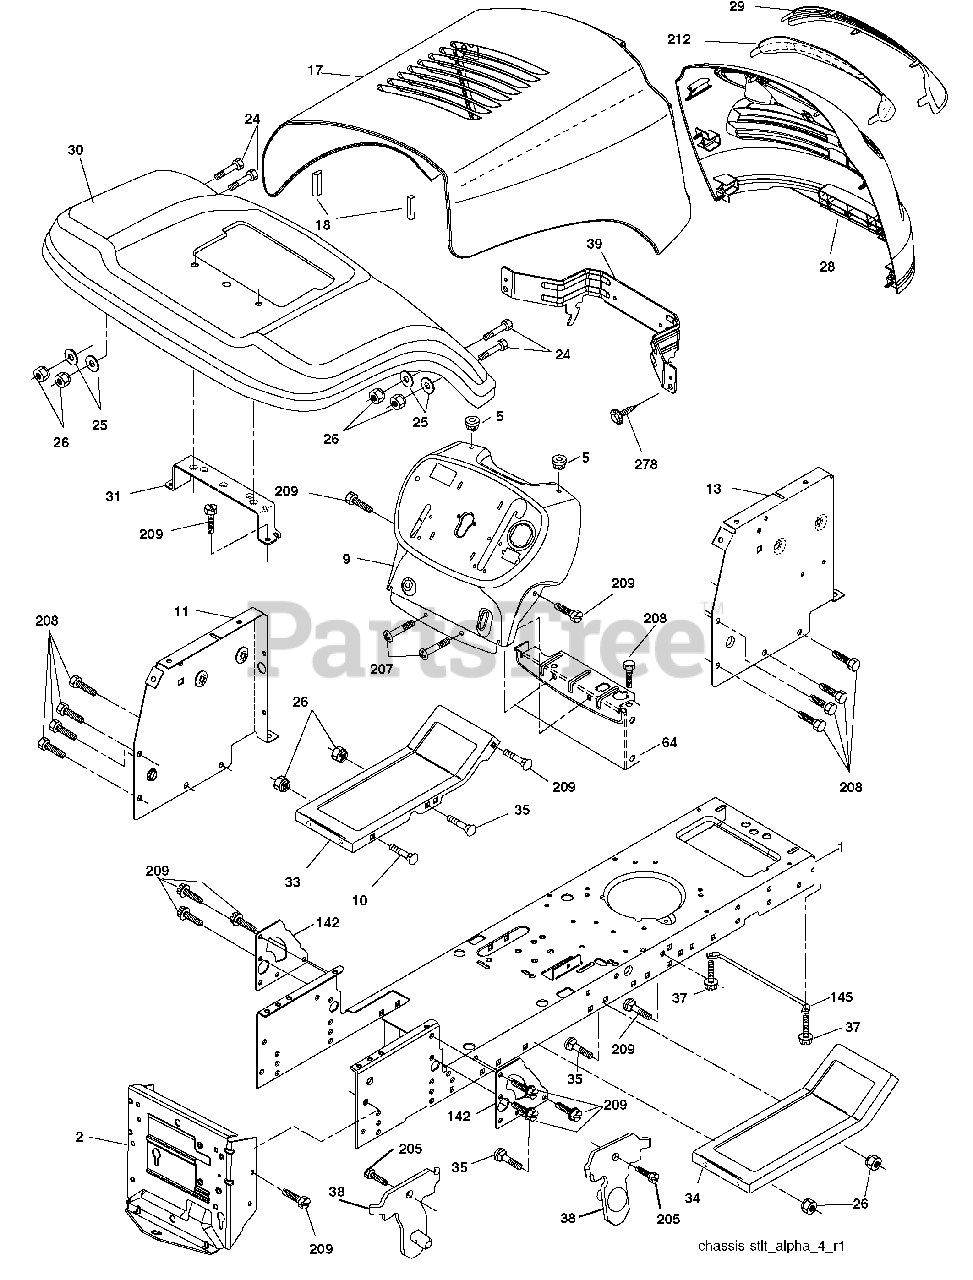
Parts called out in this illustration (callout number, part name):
1	Chassis
2	Drawbar, Stretch
5	Bumper, Hood/Dash
9	Dash
10	Bolt, Carriage 3/8-16 x 1
11	Panel Dash LH
13	Panel Slkscr Dash RH
17	Hood
18	Bumper Hood
24	Bolt Fin Hex 3/8-16 unc x 1 Gr. 5
25	Washer 13/32 x 13/16 x 12 Ga.
26	Nut Lock Hex w/Ins 3/8-16 unc
28	Grille/Lens Asm.
29	Lens Grille Bar
30	Fender
31	Bracket Fender Repl 109873X
33	Footrest Pnt LH
34	Footrest Pnt RH
35	Bolt Rdhd Sht Sqnk 3/8-16 x 3/4
37	Screw Thdrol 5/16-18 x 1/2 TYT
38	Bracket Asm. Pivot Mower
39	Bracket Pivot
64	Dash Lower
142	Plate Reinforcement
145	Rod Pivot Chassis/Hood
205	Screw Thdrol 3/8-16 x 1/2
207	Screw 5/16-18 x 1/2
208	Screw Thdrol 3/8-16 x 1/2
209	Screw Hex Wsh Thdrol 3/8-16
212	Insert Lens Reflect
278	Screw #10 x 0.750 BOS Thread
278	Plug Button Blk 359 Dia Choke
278	Plug Dome Plastic
